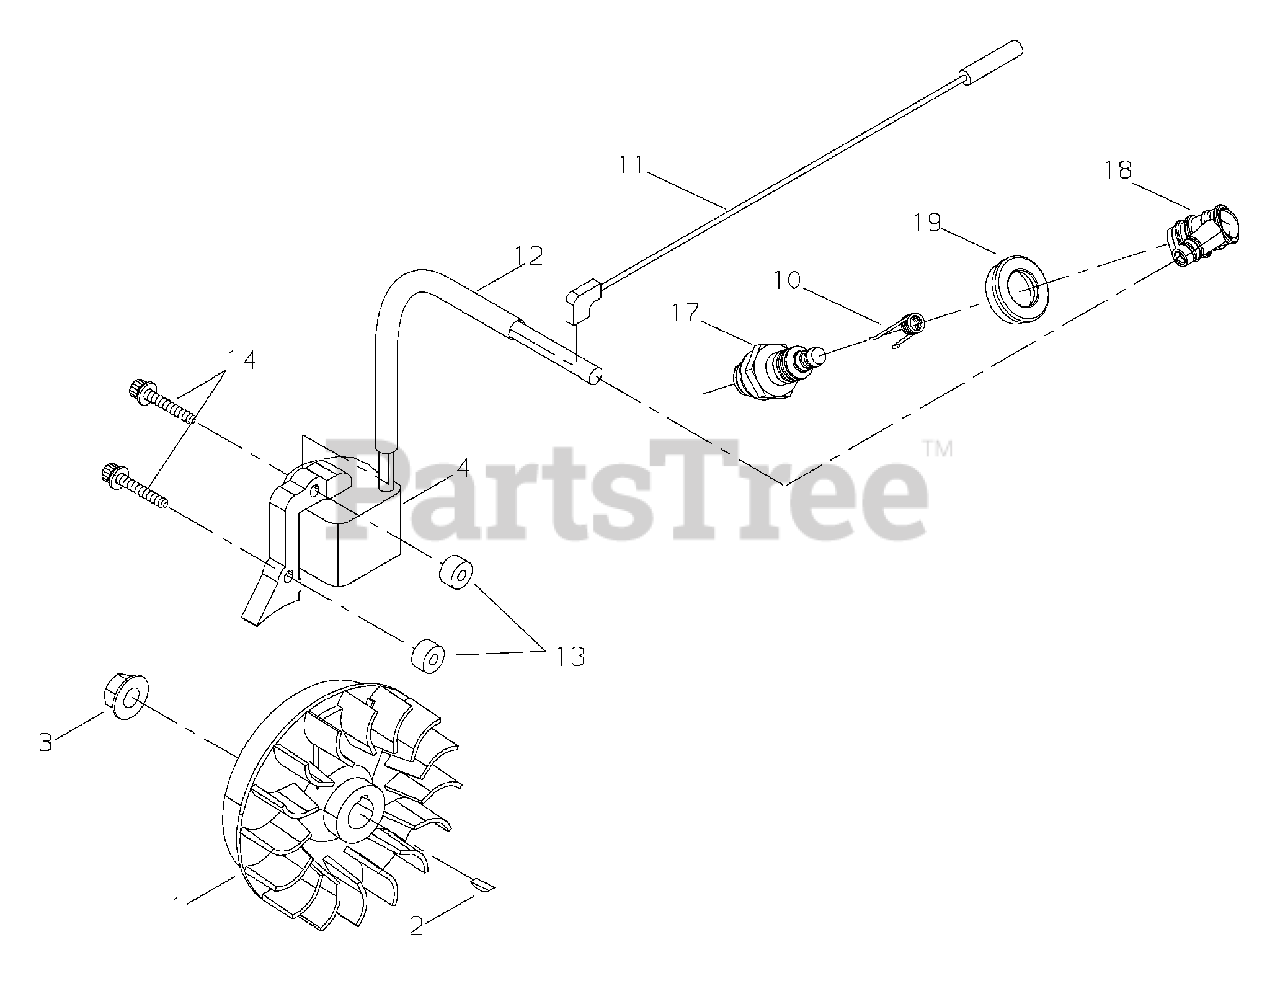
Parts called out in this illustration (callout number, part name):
1	FLYWHEEL
2	KEY, WOODRUFF 3×10
3	NUT M8
4	COIL, IGNITION
10	TERMINAL, SPARK PLUG
11	LEAD - IGNITION L= 215
12	TUBE, IGNITION COIL
13	INSULATOR 4.2×11×6
14	BOLT, ADHESIVE M4×20
17	SPARK PLUG - BPMR6A
18	CAP, SPARK PLUG
19	SEAL, SPARK PLUG
